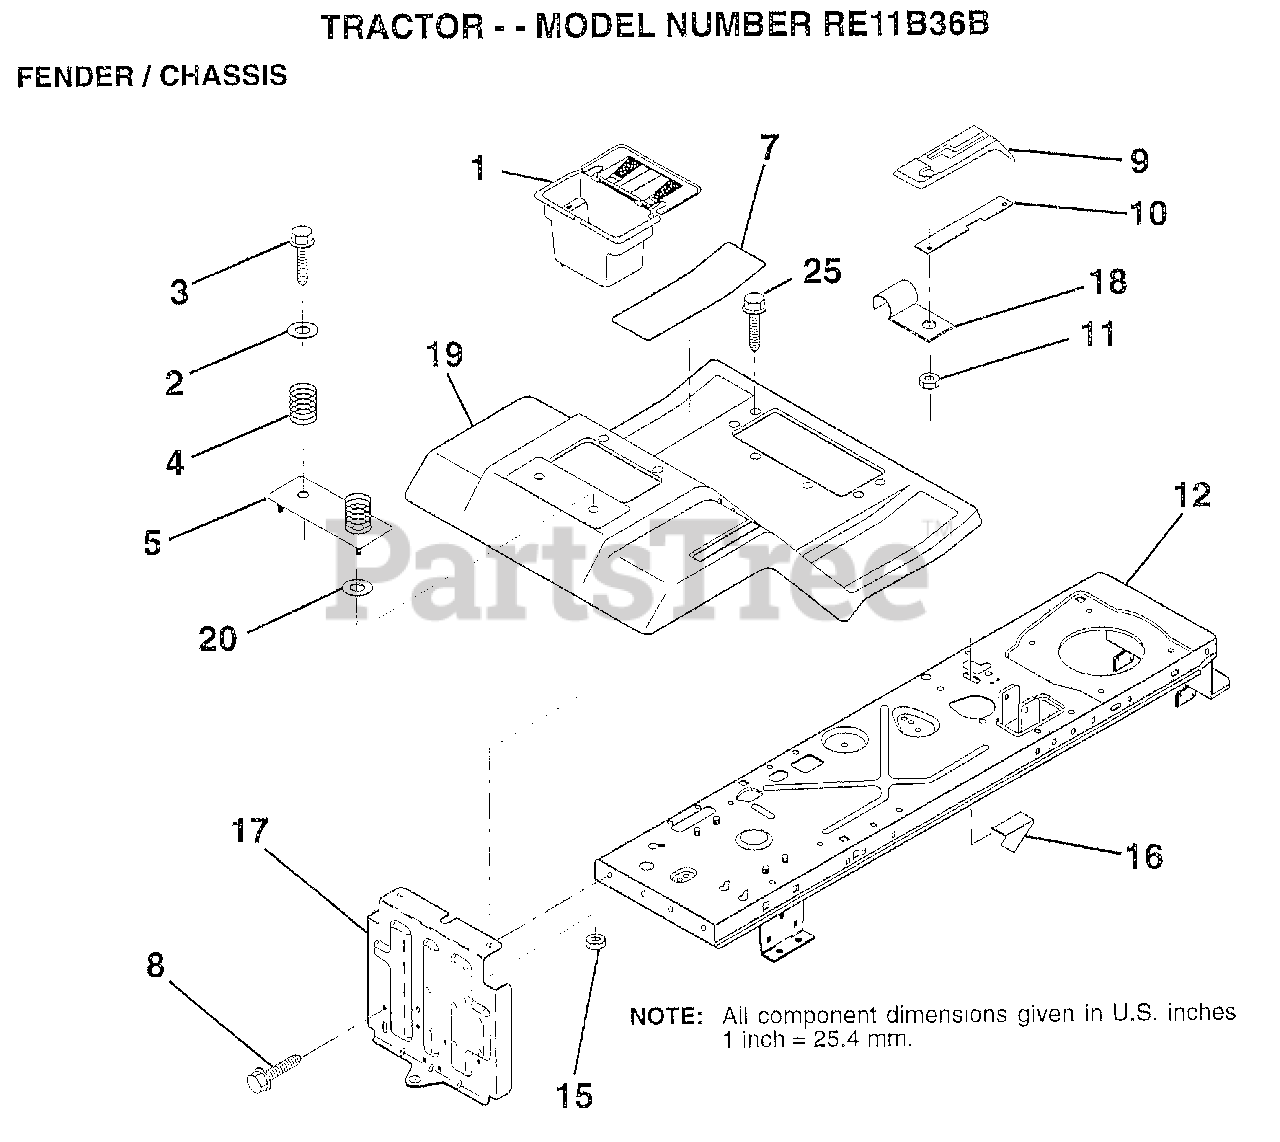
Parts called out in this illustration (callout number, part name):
1	"CASE,BATTERY.MECH"
2	WASHER
3	SCREW
4	SPRING COMPRESSIO
5	BTRY FENDER PLATE
7	PAD FOOTREST
8	SCREW
9	CONSOLE.SHIFT CONTROL
10	PLATE LOCK SHIFT
11	NUT
12	CHASSIS.WELD.ASM.
15	NUT HXKEP 1/4X20
17	DRAWBAR ASM LR
18	"CLIP,INSULATOR"
19	FENDER/FOOTREST
25	SCREW TAPPING
